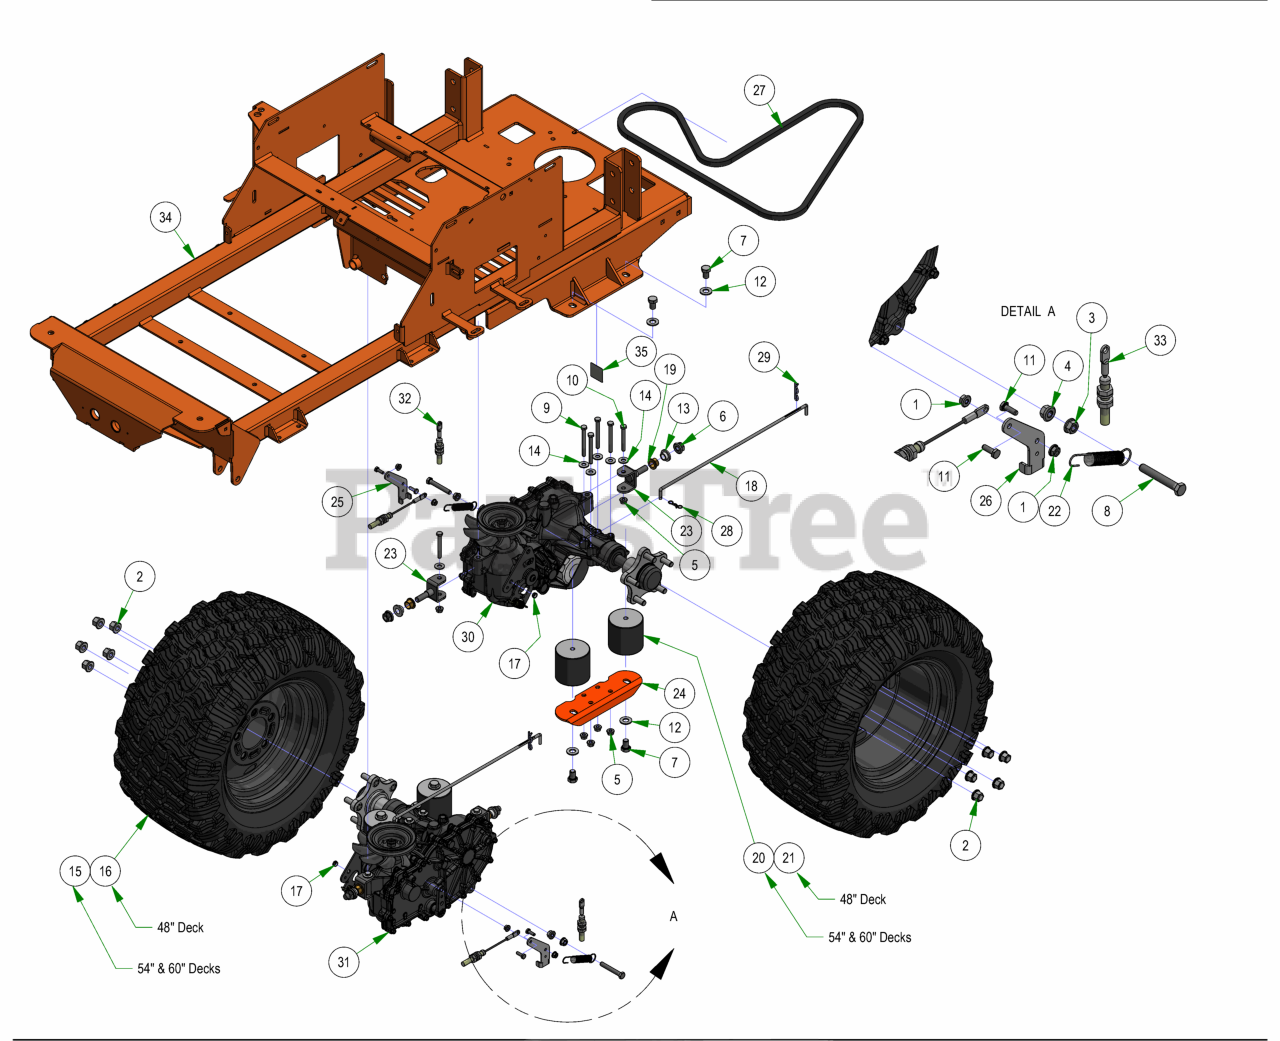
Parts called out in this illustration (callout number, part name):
1	1/4-20 NYL INSERT FLANGE LOCKNUT ZINC
2	Acorn Lug Nut
3	3/8-16 HEX SERRATED FLANGE NUT HARD/ZINC
4	3/8-16 NYLON INSERT FLANGE LOCKNUT (GR.F) ZINC
5	5/16-18 NYLON INSERT FLANGE LOCKNUT ZINC
6	1/2-13 NYLON INSERT FLANGE LOCKNUT ZINC
7	1/2-13 X 3/4 HEX CAP SCREW (GR.5) ZINC
8	3/8-16 X 2-1/2 HEX TAP BOLT (GR.5) ZINC Fully Threaded
9	5/16-18 X 3 HEX CAP SCREW (GR.5) ZINC
10	5/16-18 X 2-1/2 HEX CAP SCREW (GR.5) ZINC
11	1/4-20 X 3/4 HEX CAP SCREW (GR.5) ZINC
12	1/2 SAE FLAT WASHER (1-1/16" OD) GR.8 ZINC YELLOW
13	.525 ID SHOULDER WASHER NYLON
14	5/16 USS FLAT WASHER (7/8 OD) ZINC
15	23x9-12 Reaper Turf
16	23x11-12 Reaper Turf Assembly
17	Drive Arm Transaxle Spacer
18	Neutral Rod
19	.627 ID X .753 OD X .500 LGTH X 1.000 FLG OD X .094 FLG THICK
20	Vibration Mount-Green Dot
21	Vibration Mount- Red Dot
22	Brake Return Spring
23	Maverick Rear Transaxle Pivot Bracket
24	Rear Suspension Transaxle Mount
25	Brake Arm Ext (Left)
26	Brake Arm Ext (Right)
27	75.8" Pump Belt
29	Neutral Rod Clip
30	2025 LH 3200 Transaxle
31	2025 RH 3200 Transaxle
32	2021 Load Balanced Brake Cable 1
33	2021 Load Balanced Brake Cable 2
34	2025 Maverick Frame
35	Patent Decal
